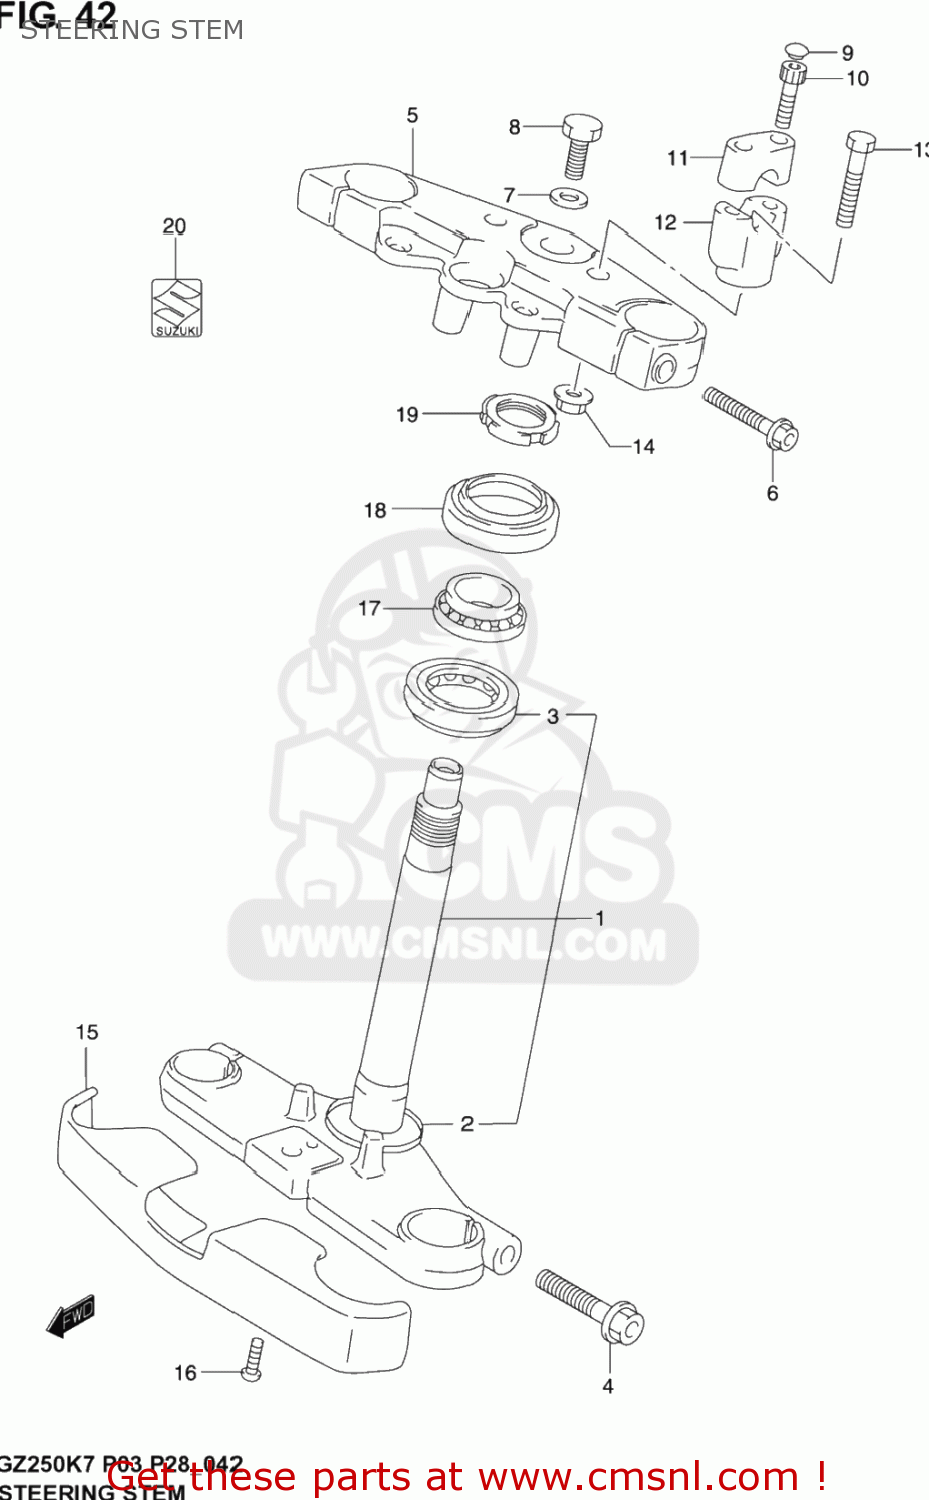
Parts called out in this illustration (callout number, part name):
1	STEM, STEERING
2	SEAL,STEERING LWR
3	BEARING(30X55X17)
4	BOLT
5	HEAD,STEERING STEM
6	BOLT
7	WASHER
8	BOLT,STEERING STEM HEAD
9	CAP(OD:11)
10	BOLT
11	HOLDER,HANDLE UPR
12	HOLDER, HANDLE LOWER
13	BOLT
14	NUT
15	COVER, FRONT FORK UNDER
16	SCREW(6X16)
17	BEARING(25X47X15)
18	DUST SEAL,STEERING UPR
19	NUT,STEERING STEM(25X44X10)
20	EMBLEM,S
